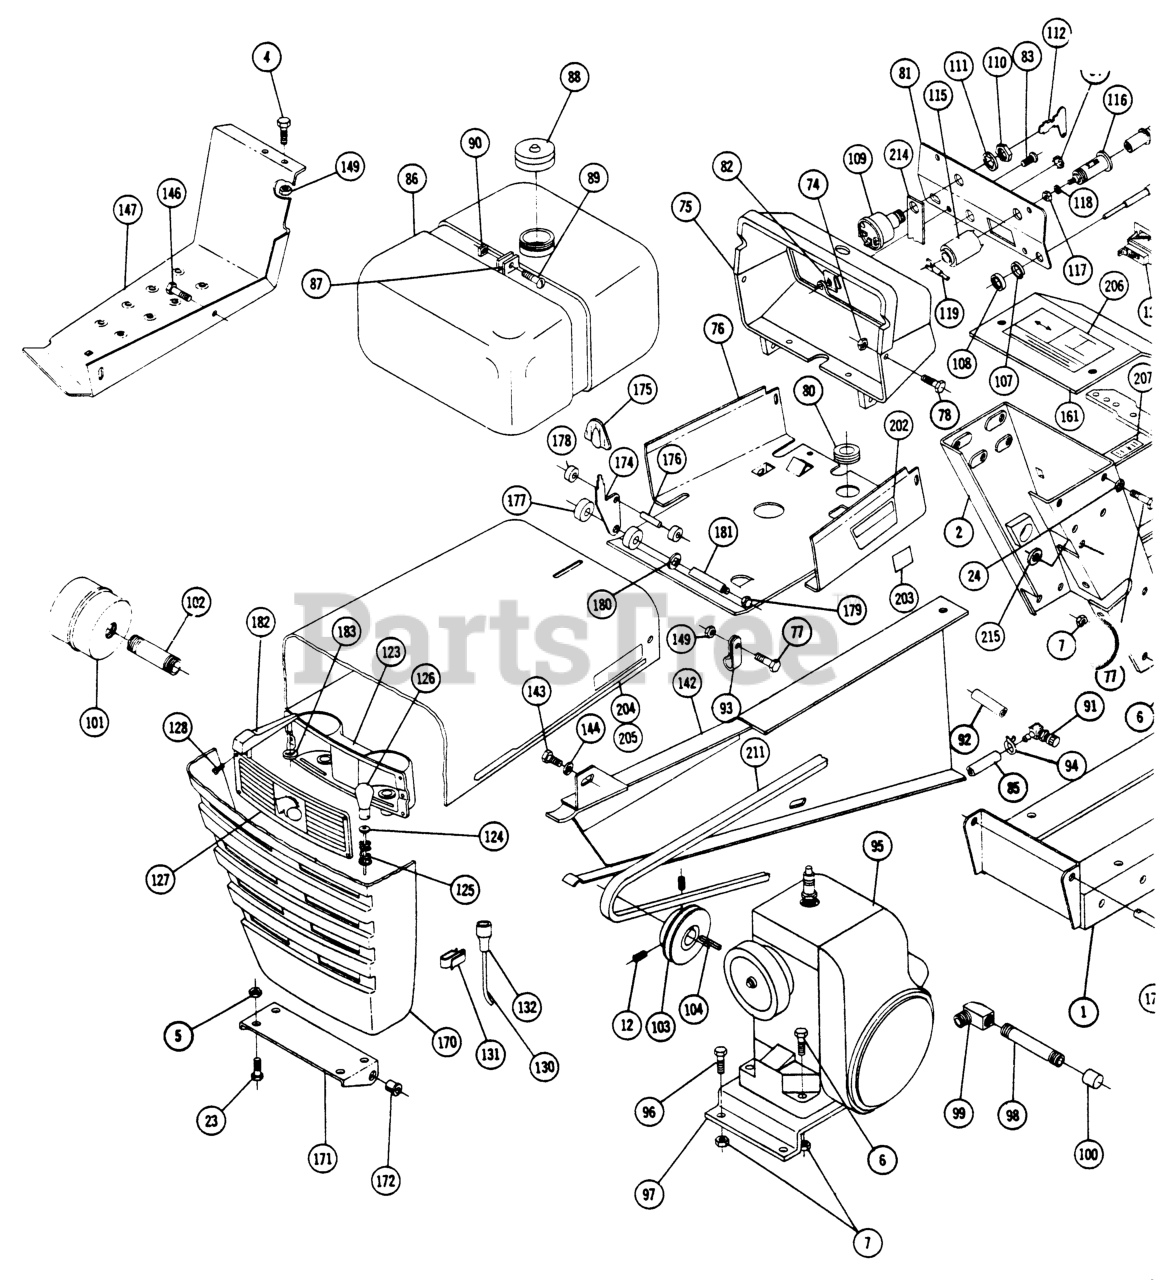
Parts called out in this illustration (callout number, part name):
1	Ass-y.Frame
2	Hoodstand
3	Cover-Dust
4	Bolt 5/16-18 x
5	Nut-Nylok
6	Bolt 3/8-16 x 1
7	3/8-16 E.S.
8	Bolt 3/8-16 x 3/4
9	Washer
10	Lockwasher
11	Pulley Trans
12	Set Screw
13	WOODRUFF KEY
14	Bolt 3/8-16 x 7/8
15	Hub Wheel
16	WOODRUFF KEY
17	Screw-Set
18	3/8-16 Jam Nut
19	AXLE-FRONT
20	Zerk
21	FITTING-GREASE
22	PIN AND PLATE ASM
23	Bolt Hex 5/16-18
24	Lockwasher
25	R.H. Spindle
26	L.H. Spindle
27	E-RING
28	Support
29	BEARING-BRONZE
30	Bolt 3/8-16 x 1
31	ASSY UPPER STEER R
32	Collar
33	Set Screw Nylok
34	Assy-Steering
35	WASHER-SHIM
36	WASHER
37	BEARING-FLANGED
38	Tie Rod-R.H.
39	Tie Rod-L.H.
40	Locknut 3/8-24
41	Idler Arm & Shaft
42	Arm Clutch Rod Pivot
43	SPIROL PIN
44	PULLEY-IDLER
45	Bolt 3/8-16 x 1 5/8
47	Rod Clutch
48	Rod
49	Trunnion
50	Cotter Pin
51	Spring
52	Ass-y Lock-Brake
53	Pedal
54	Hairpin
55	Lift Lever
56	LOWER PLUNGER R
57	PLUNGER ROD
58	Roll Pin
59	SPRING-COMPRESSION
60	Guide-Rod
61	Cap
62	Grip
63	Hairpen
64	Quadrant
65	ROD-LIFT CONTROL
66	KNOB-LIFT CONTROL
67	Conduit
68	Hitch
69	Pin
70	RING-SNAP, EXTERNAL
71	SPACER
72	BATTERY BOX ASSY R (NS)
73	LINK BATTERY CLAMP
74	Nut-Nylok
75	Housing
76	Support-Fuel Tank
77	Bolt Hex 5/16-18
78	Bolt 1/4-20 x 5/8 Whizlock
79	Bushing
80	Grommet
81	Panel
82	SPEED NUT
83	Screw-Self #10 10-16
84	Plug Button
85	Fuel Hose
86	Fuel Tank
87	Clamp-Tank
88	Cap
90	Nut Square
91	S/A FUEL VALVE
92	Hose
93	Clip
94	CLAMP CORBIN 7/16
95	Ass-y Engine-Lauson
96	Bolt, 3/8-16 x 1/2
97	Base Engine
98	Nipple 3/8 x 5
99	ELBOW-STREET
100	Cap
101	MUFFLER
102	Nipple 1" Pipe x 2"
103	PULLEY
104	Key
105	Choke-Control
106	Control-Throttle
107	Lockwasher 9/16
108	RING NUT
109	SWITCH
110	Nut
111	Lockwasher 6/16
112	Key-EL
113	Cigar Lighter
114	Knob & Plug
115	SHELL CLAMP
116	Socket
117	Nut #8-32
118	Lockwasher
119	Wire
120	Battery
121	Wiring Harness
122	Ground Wire
123	ASSY REFLECTOR HOUSI
124	WIRE ASSY
125	SPRING
126	BULB
127	Lens
128	Pan HD Swage
129	Switch
130	Harness
131	SPEED CLIP
132	CONNECTOR 3 WIRE
133	Base
134	Lens
135	Bulb
136	Mounting Pad
137	CONNECTOR 2 WIRE
138	SPEED CLIP
139	Bolt #10-32
140	Nut #10-32
141	Lockwasher
142	Belt Guard
143	Bolt Hex 7/16-4 x 3/4
144	Lockwasher 3/8
145	Bracket
146	Bolt, 5/16-18 x 1/2
147	Footrest R.H.
148	Footrest L.H.
149	Nut 5/16-18
150	BRACKET
151	Bolt-Carriage 5/16-18
152	Latch Fender
153	Spring Fender Latch
154	NYLINER BUSHING
155	Pin
156	Hairpin
157	BRACKET FENDER LATCH
158	Bolt-Hex 1/4-20
159	Nut, 1/4-20
160	Stop-Fender Latch
161	Cover Plate
162	Bolt, 1/4-20 Whizlock
163	Fender
164	BUSHING-FLANGED
165	Bolt 3/8-24 x 7/8 Hex
166	SPACER
167	GROMMET
168	Seat
169	Washer
170	Ass-y Hood
171	Hood-Hinge
172	NYLINER BUSHING
173	Rod Pivot
174	LEVER HOOD LATCH
175	KNOB
176	SPIROL PIN
177	Roller Rubber
178	Roller
179	Nut-Hi Crown
180	SPEED NUT
181	Rod Latch
182	Hood Ornament
183	SPEED NUT
184	Wheel and Tire
185	Wheel
186	Tire
187	VALVE TUBELESS
188	Lug Nut
189	Wheel, Tire & Tube
190	WHEEL RIM
191	Bearing
192	Tire
193	Tube
194	WASHER
195	Hub Cap
196	Steering
197	CAP INSERT
198	ROLL PIN 1/4 X 1-1/4
199	Key
200	WASHER-BOWED
201	COLLAR
202	Decal-"8"
203	Decal-"10"
204	Decal-Hood R.H.
205	Decal-Hood L.H.
206	Decal Shift Pattern
207	Deal-Seat Latch
208	Decal
209	Decal
210	Pin-Tool
211	V BELT
212	Cotter Pin
213	CLIP-WIRE
214	Insulator
215	SPACER
